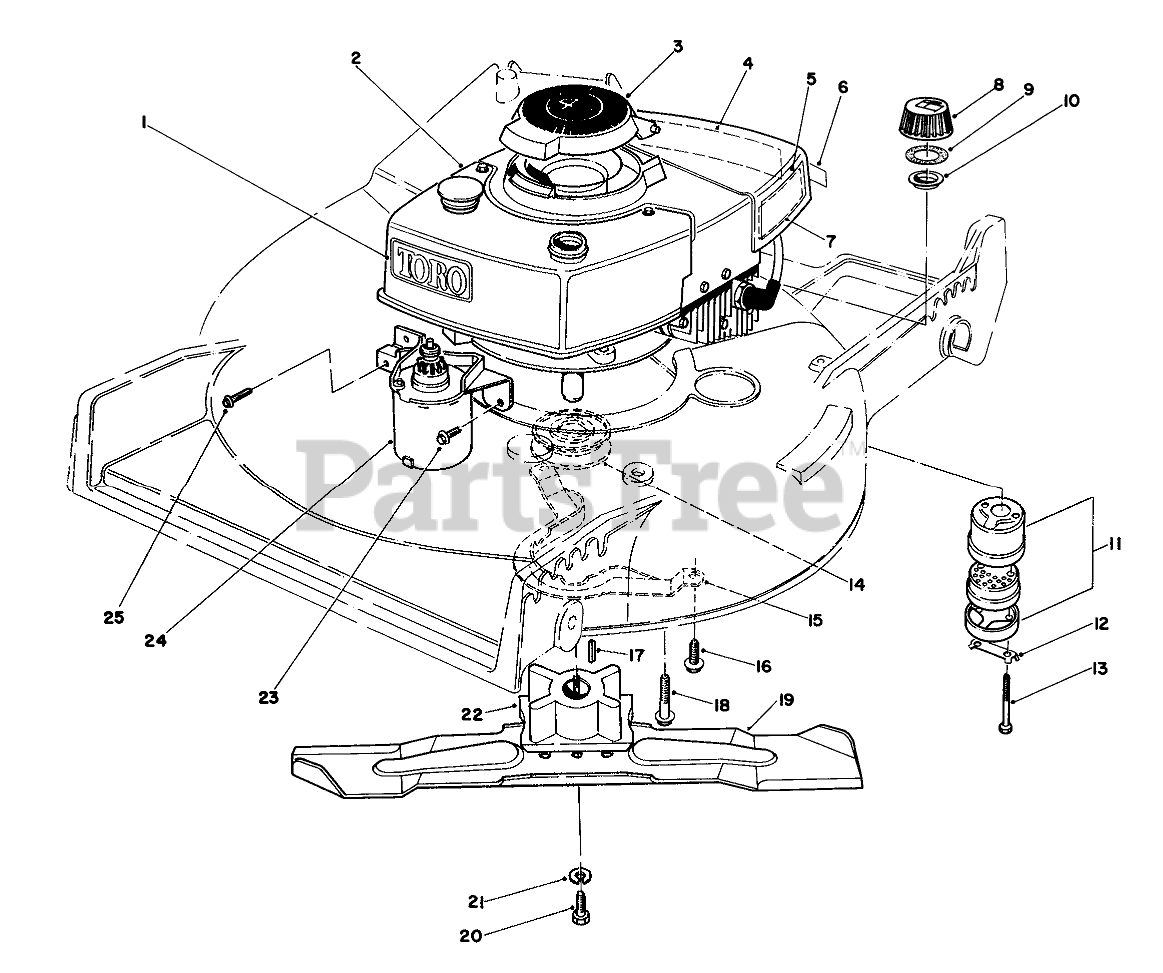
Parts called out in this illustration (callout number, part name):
1	Decal Tow
2	Engine
3	COVER ASM
4	Decal Maintenance
5	Decal-Maintenance
6	Decal-Primer Bulb
7	Decal-Maintenance
8	Gas Cap (Incl. Ref. #9 & 10)
9	GASKET
10	GAS CAP BAFFLE
11	Muffler Assembly (Incl. Ref. #12 & 13)
12	CLIP - LOCKING
13	SCREW-HH
14	Pulley
15	BELT GUIDE
16	Screw
17	KEY-SQUARE
18	3/8-16 X 2 CAPSCREW
19	BLADE-21in
20	SCREW-BLADE
21	WASHER-LOCK
22	BLADE RETAINER(DEEP)
23	SCREW
24	STARTER MOTOR ASM
25	Screw
